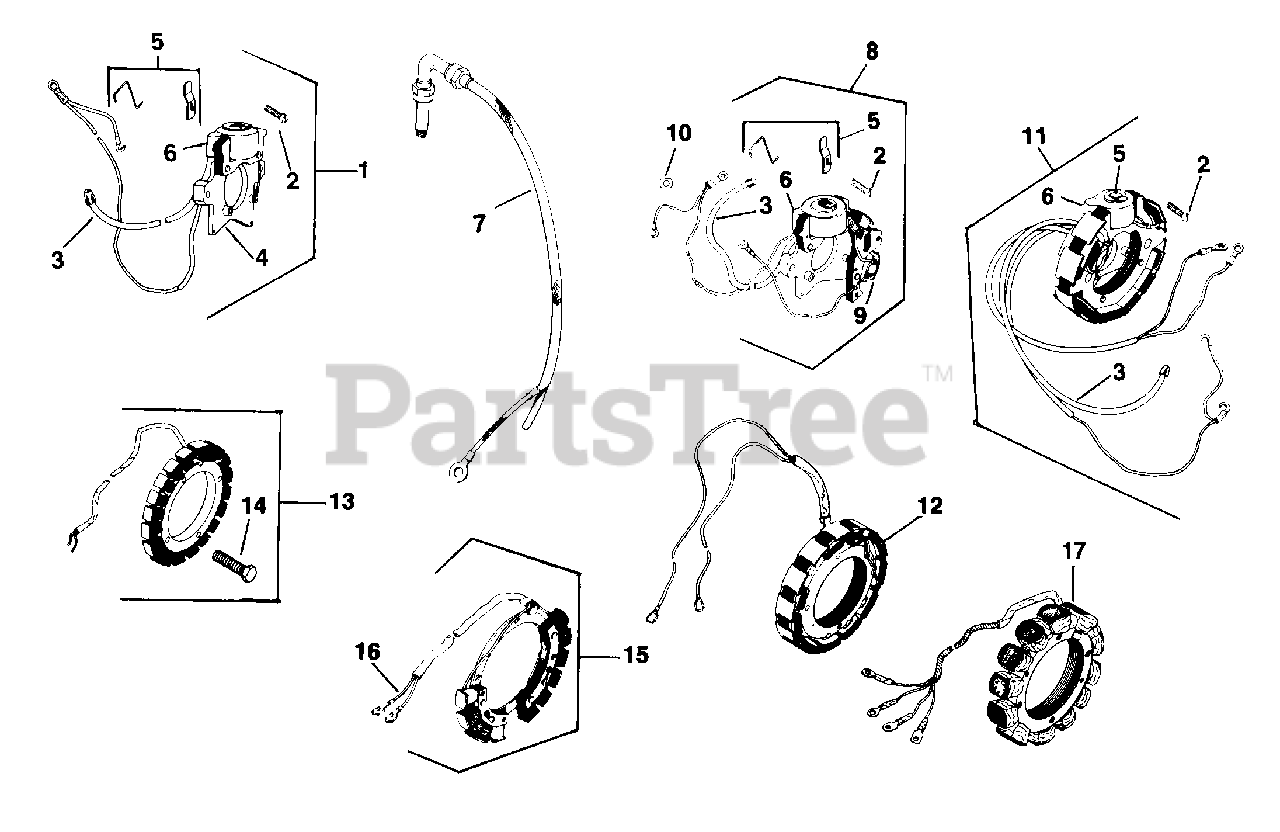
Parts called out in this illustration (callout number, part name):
3	LEAD - DISCONTINUED
5	KIT, CLIP - DISCONTINUED
6	KIT, COIL
11	KIT, STATOR
